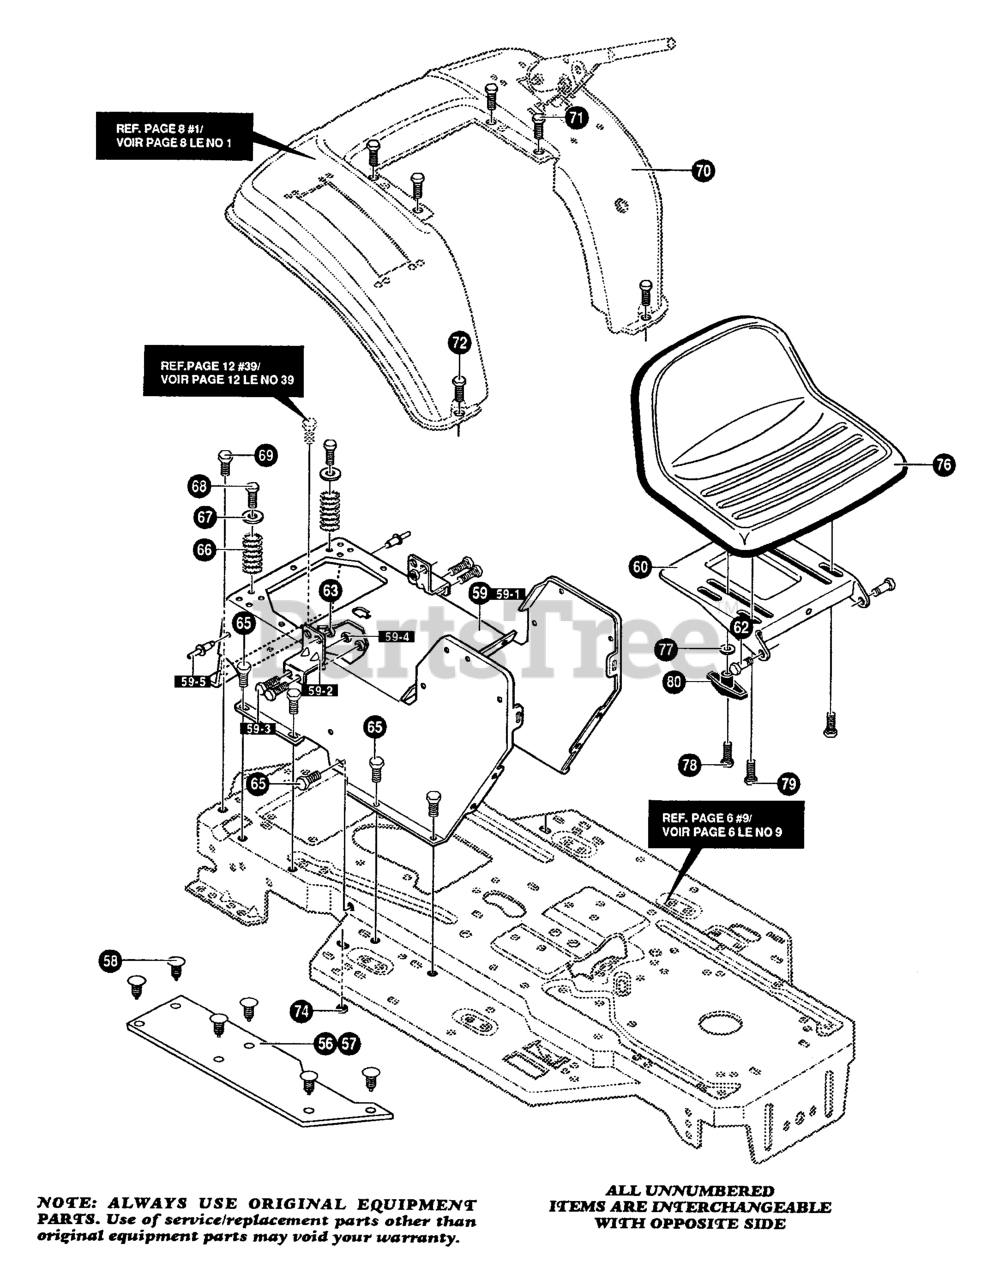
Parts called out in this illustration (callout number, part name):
56	FOOT PAD, LH
57	FOOT PAD, RH
58	FASTENER
59	ASSY, CONSOLE
59-2	BRKT, SEAT SUPPORT
59-3	SCREW
59-5	RIVET
60	PLATE, SEAT
66	SPRING, SEAT
67	WASHER
69	SCREW
70	FENDER
77	WASHER
80	HANDLE
